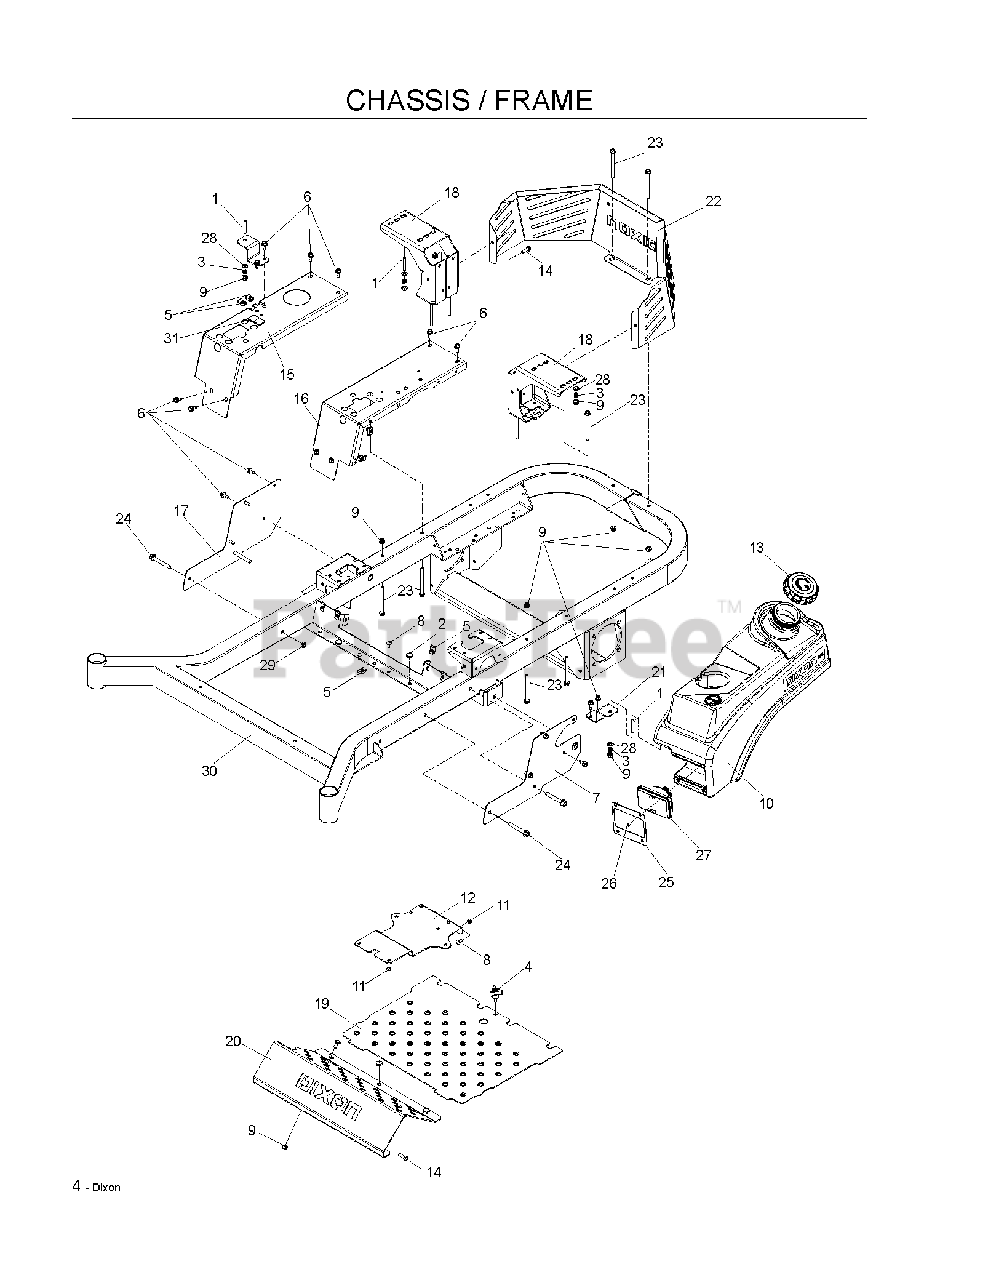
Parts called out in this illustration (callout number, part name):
1	STUD, 5/16C
2	GROMMET, BUMPER
4	KNOB W/STUD
5	U-CLIP 5/16-18 NUT RETAINER
6	BOLT 5/16-18 X 3/4
7	SIDE, LT, BL
8	RHSSNB, 1/4-20X5/8
9	5/16-18 NYLOC FLANGE NUT
10	TANK, FUEL, LT
11	NUT 1/4-20 NYLOC
12	BATTERY MOUNT
13	Fuel Cap, HTC
14	BOLT 5/16C X 3/4" CARRIAGE
15	PANEL, FILLER, RT, DK BLUE
16	PANEL, FILLER, LT - BLUE
17	SIDE, RT, BL
18	MOUNT, TANK, RR
19	FLOOR PAN W/DECALS
20	PLATE, FOOTREST, BL
21	SUPPORT, TANK, FT, BLK
22	GUARD, REAR, DIXON, BL
23	HHFS 5/16-18 X 3 3/4
24	HHFS 3/8-16 X 2 3/4
25	PLATE LIGHT
26	SCR #10-24 X 3/8 SKT HD BLK OX
28	FLAT WASHER 5/16 SAE
29	NUT HEX 3/8-16 NYLON, THIN
30	FRAME W/DECALS, 72
31	PLUG DASH
